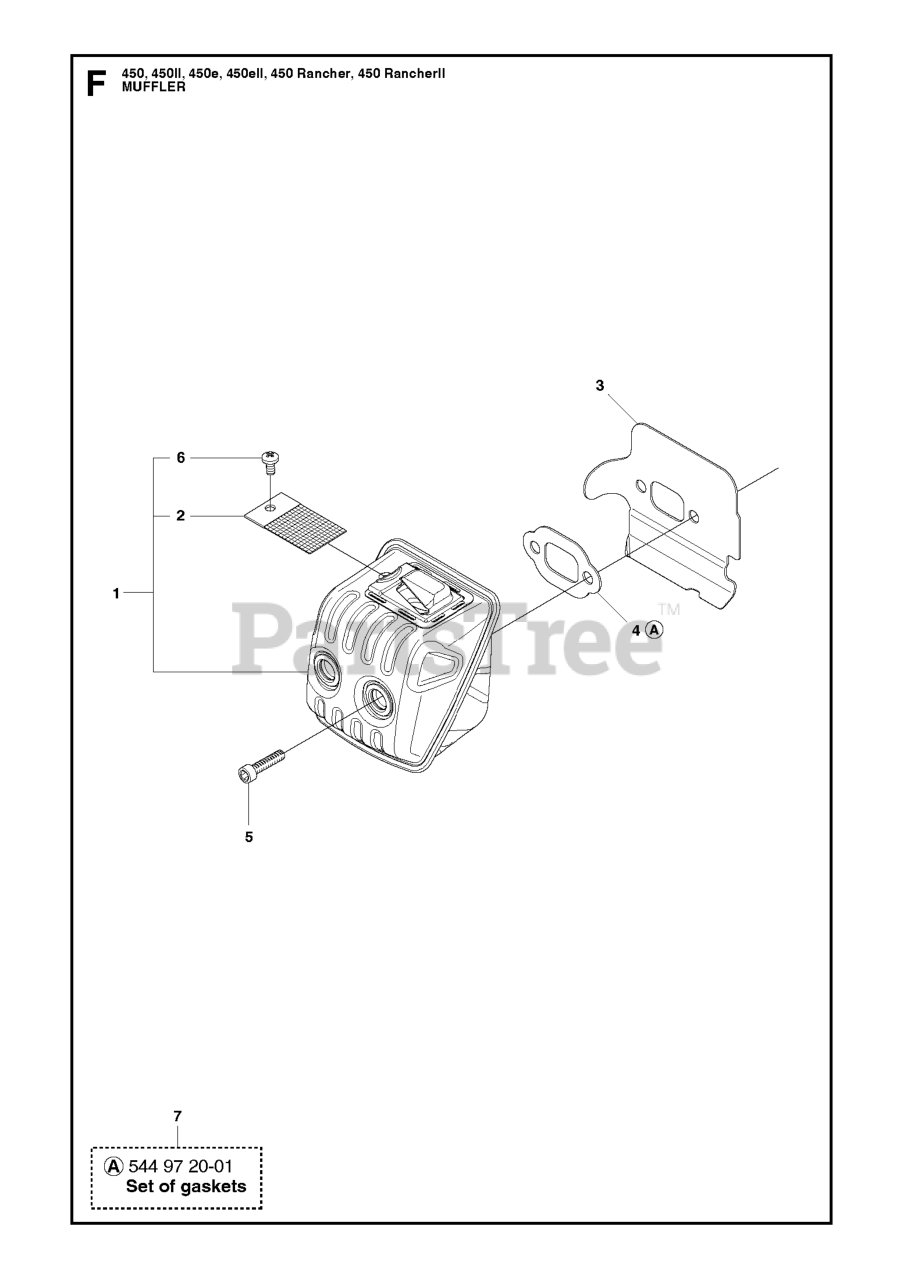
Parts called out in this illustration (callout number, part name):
1	SEAT
1	MUFFLER ASSY
2	SEAT PIVOT BRKT
3	BOLT, HEX 3/8-16X1
3	HEAT DEFLECTOR
5	SCREW MC6S 6X16
6	NUT
7	SPRING COMPRESSION
7	GASKET KIT
8	SCREW 3/8-16X1
9	WASHER
10	PAN SEAT
11	KNOB.SEAT.ADJ.WINGNUT
12	BRKT.MNTNG.SWITCH.SEAT.BLACK
14	BOLT.ROUND.HEAD.SQUARE.NECK
15	SPACER SPLIT
16	SPRING COMPRESSED
17	NUT T
21	BOLT.SHOULDER.5/16-18
22	NUT.71038.31-18.HEX.NYLOCK
25	BOLT,SHOULD
